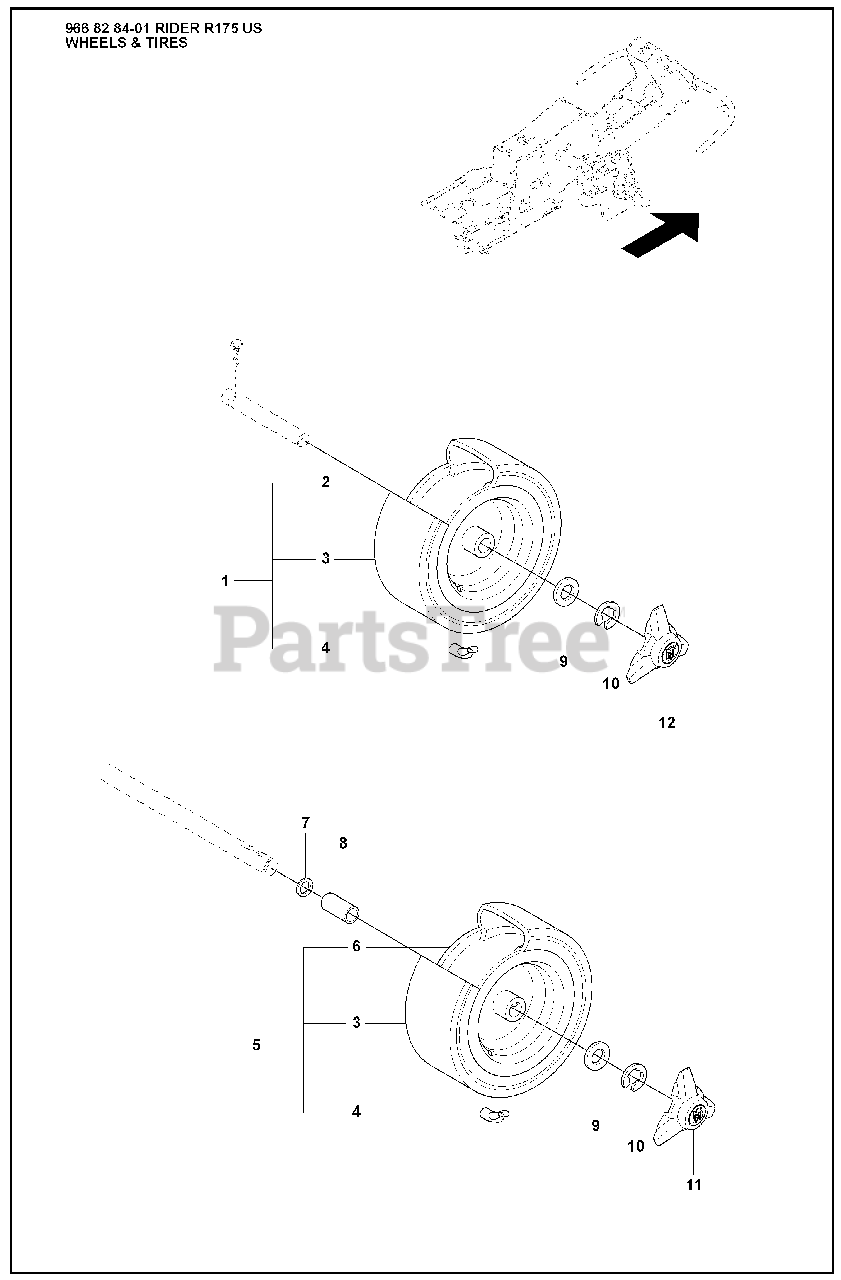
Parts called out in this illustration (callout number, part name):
5	WHEEL
6	RP RIM
10	SPACE SLEEVE
12	RETAINING RING
